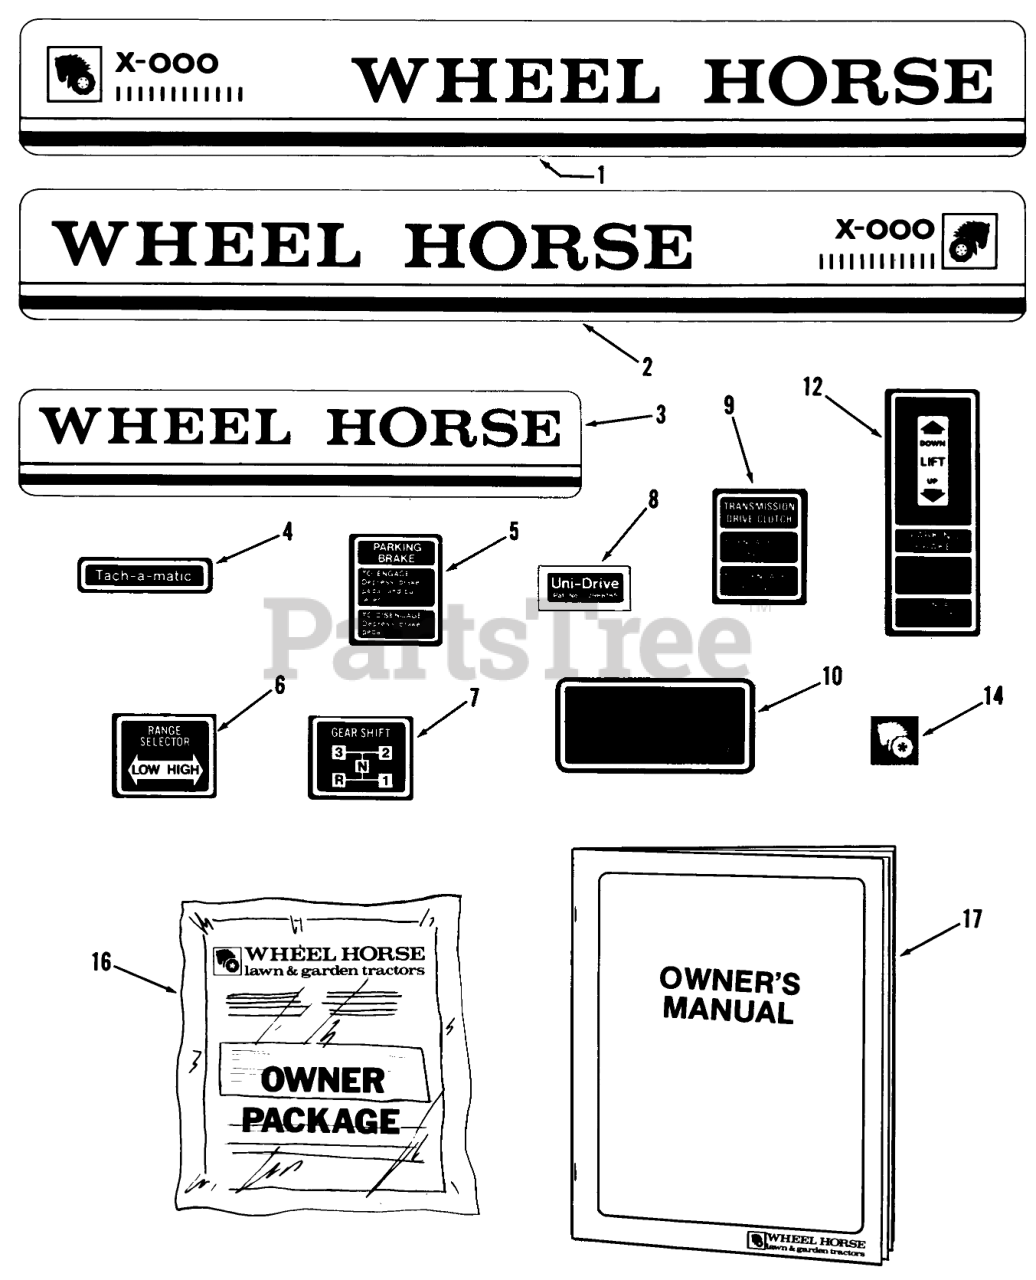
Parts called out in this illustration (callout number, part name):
1	Decal LH C-145 Automatic
1	DECAL-HOOD C-175 LH
1	Decal LH C-85 8-Speed
1	Decal LH C-105 8-Speed
1	Decal LH C-125 8-Speed
1	Decal LH C-175 Twin 8-Speed
2	Decal RH C-145 Automatic
2	Decal RH C-175 Twin Automatic
2	Decal RH C-85 8-Speed
2	DECAL-HOOD C-105 RH
2	DECAL-HOOD C-125 RH
2	Decal RH C-175 Twin 8-Speed
3	DECAL-REAR
4	DECAL-TACHAMATIC
5	DECAL-PARKING BRAKE
6	DECAL HI-LO
7	DECAL-SHIFT
8	Decal-Unidrive
9	Decal-Transmission Clutch
10	Decal-Maintenance
12	Decal-Parking Brake & Lift
14	DECAL-LOGO
16	Loose Parts Package C-105, C-125 C-145 Only
16	Loose Parts Package C-175 Twin Only
16	Loose Parts Package C-85 Only
17	Tractor Owner-s Manual (Alternate 810268R1)
